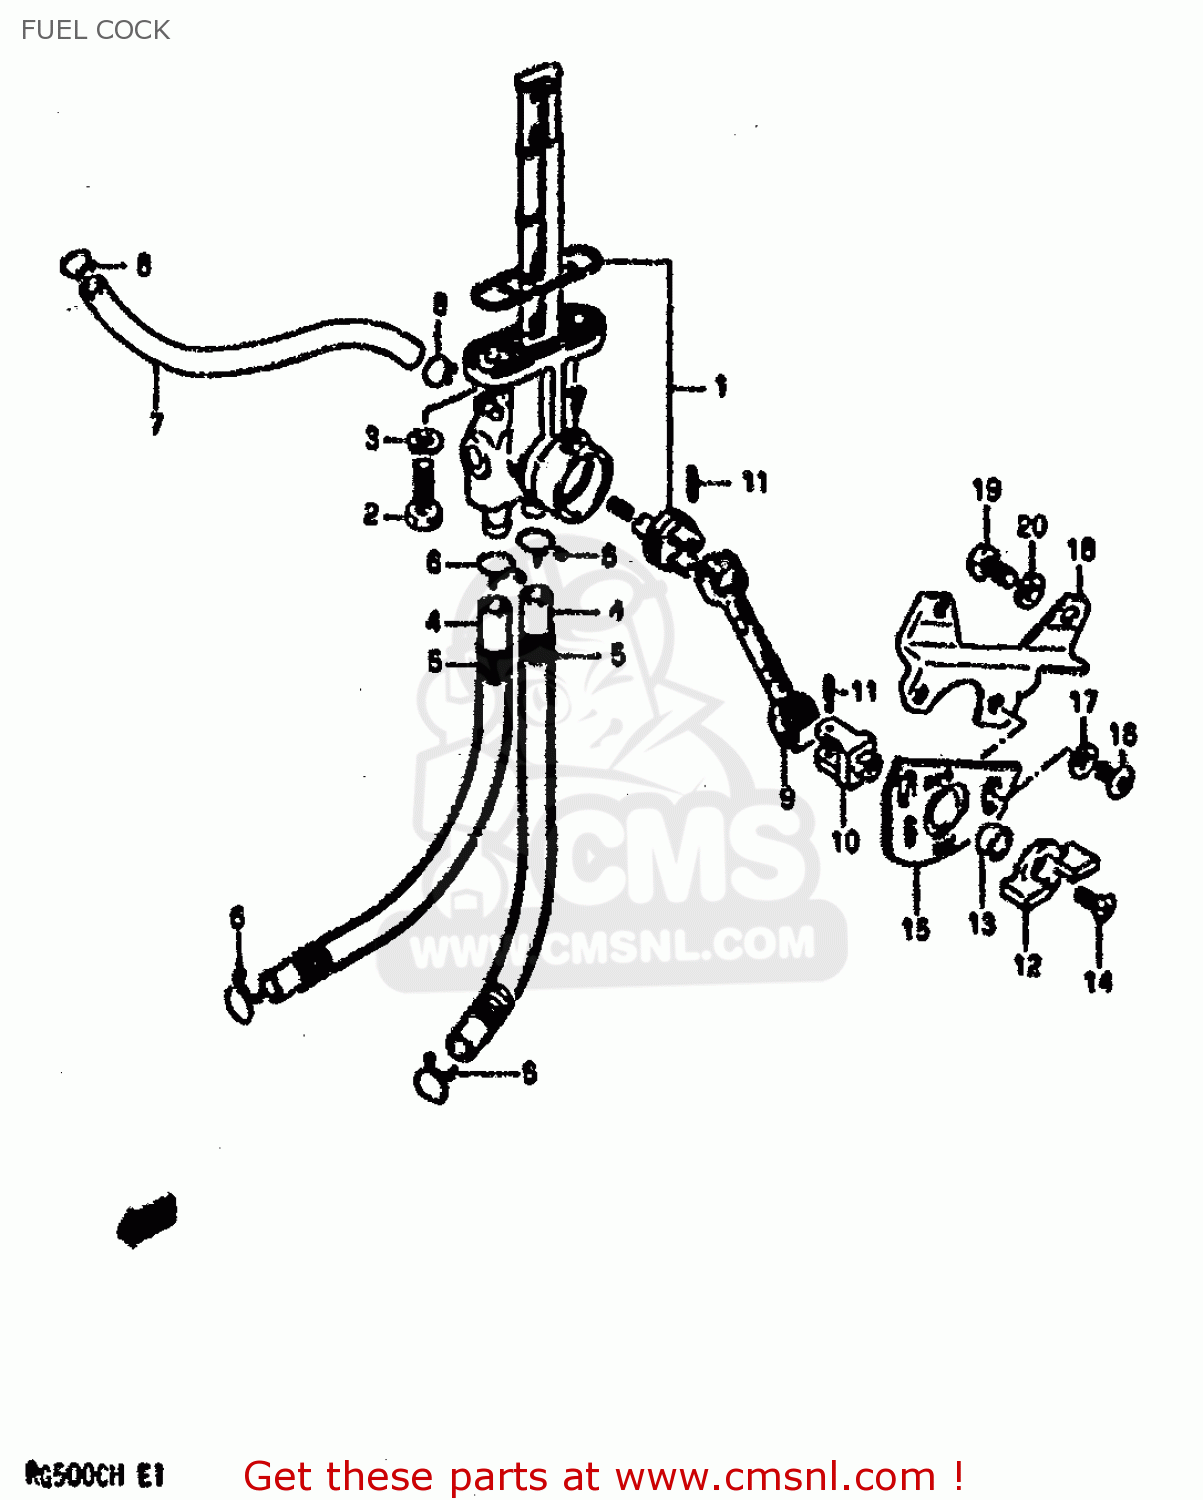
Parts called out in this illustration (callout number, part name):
1	2
2	BOLT(6X20)
3	GASKET
4	HOSE
5	SPRING
6	CLIP
7	HOSE
8	CLIP
9	JOINT,FUEL COCK
10	YOKE,FUEL COCK
11	PIN
12	HANDLE,FUEL COCK
13	BUSH,FUEL COCK HANDLE
14	SCREW 5X12
15	PLATE,HANDLE
16	SCREW
17	WASHER
18	PLATE,FUEL COCK
19	SCREW
20	WASHER
